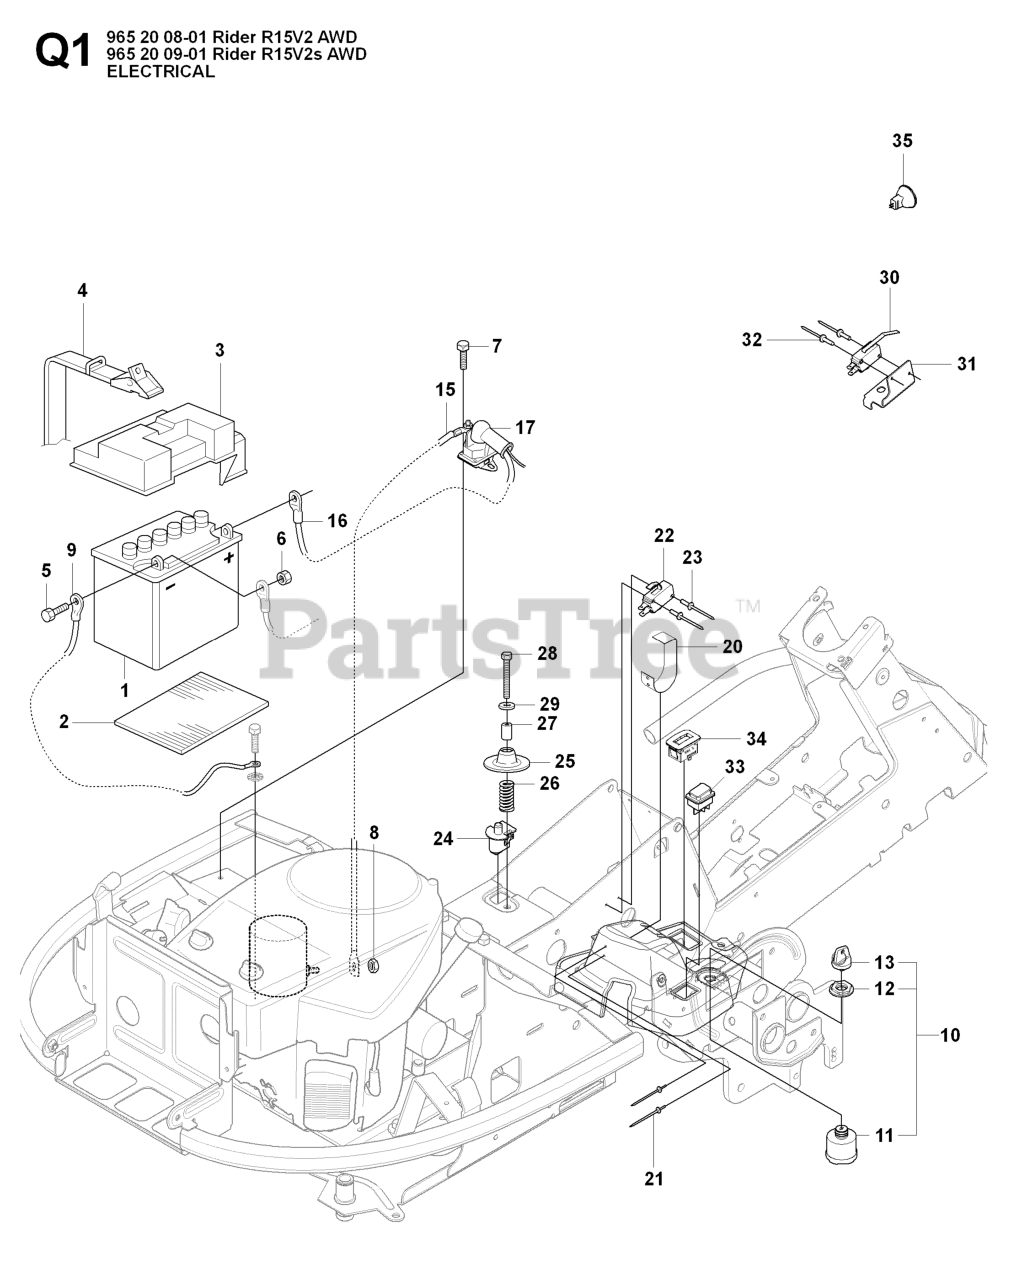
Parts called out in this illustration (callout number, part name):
1	BATTERY - DRY
10	IGNITION SWITCH
11	IGNITION SWITCH
13	IGNITION KEY
22	%BRAKER
27	SPACER TUBE
28	SCREW
29	WASHER BRB 8.4X17
30	RP MICRO SWITCH
